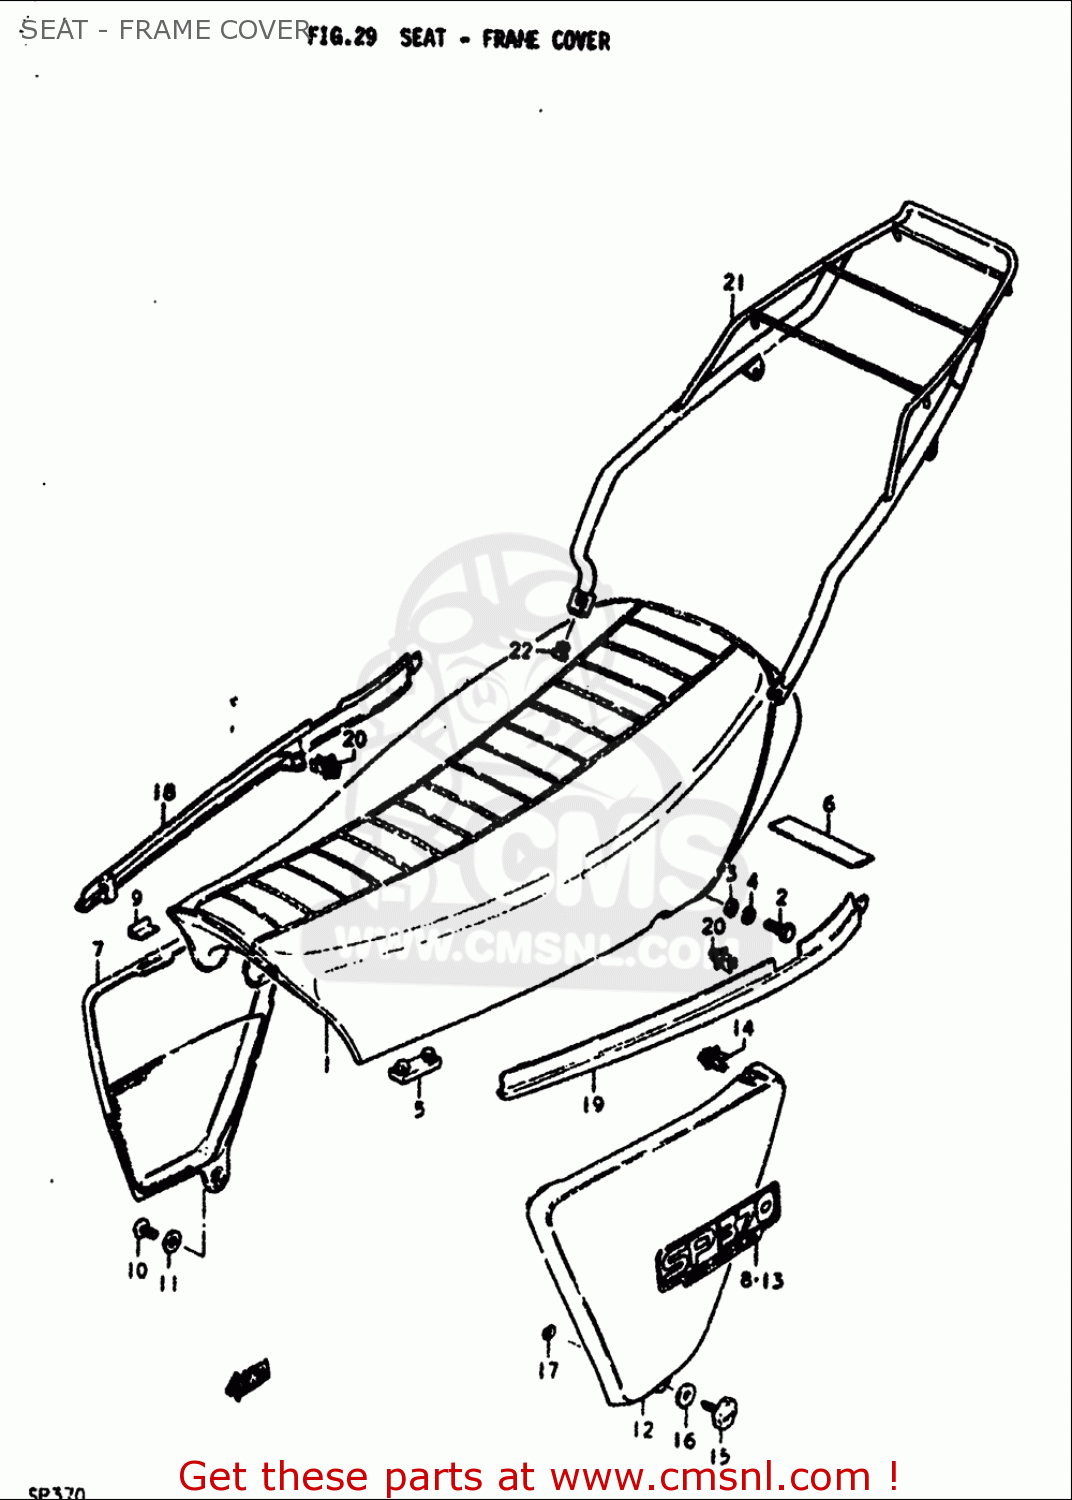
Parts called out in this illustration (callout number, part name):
2	BOLT
3	WASHER
4	WASHER,LOCK
5	CUSHION
7	COVER,FRAME,R(BLACK)
9	CUSHION,FRAME COVER
10	SCREW
11	WASHER(6.5X18X1.6)
12	COVER,FRAME,L
14	CLAMP
15	KNOB,FRAME COVER,R
16	WASHER
17	NUT
20	CLAMP
22	CAP(OD:17)
